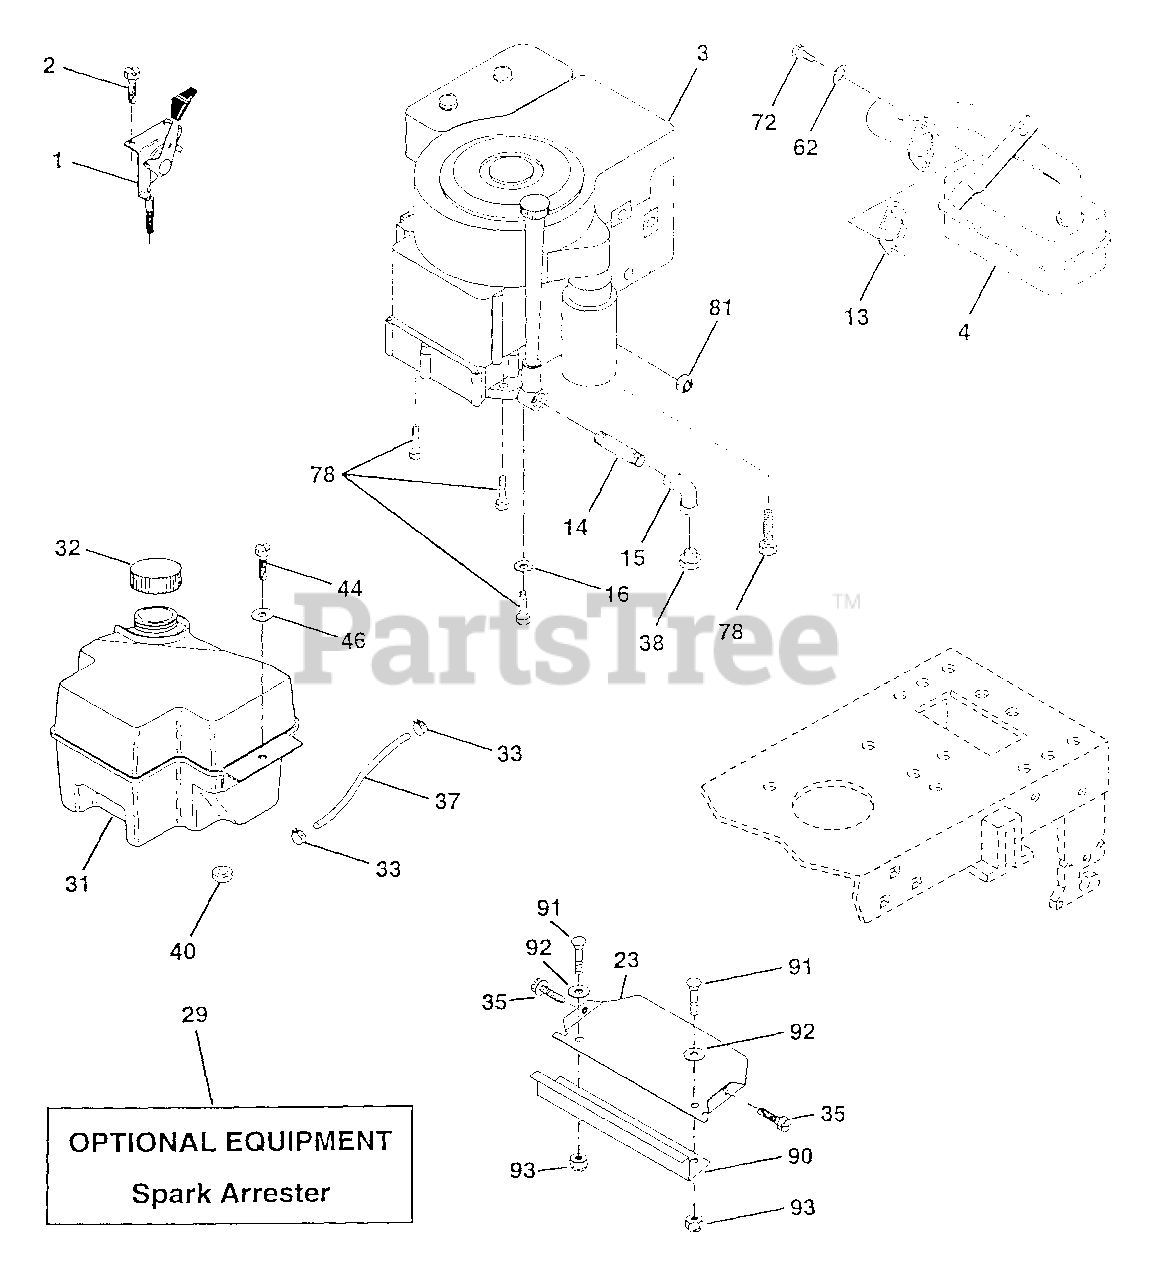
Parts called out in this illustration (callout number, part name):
1	Control Th/ch 23 5 LH Flag (AYP part number)
2	Screw Hex Thd Cut 1/4-20 x 5/8 T
3	Engine B&S
4	Muffler LT B&S 14.5
13	Gasket Eng 1 313 Id Tin Plated
14	Nipple Pipe 3/8 Npt X 3"
15	Elbow Std 90 Degree 3/8-18 Npt
16	Washer Lock Ext Tooth 3/8
23	Shield Heat
29	Kit Spark Arrestor (Flat Scrn)
31	Tank Fuel Front 2 00
32	Cap Asm Fuel W/sym Vented
33	Clamp Hose Black
35	Screw
37	Line Fuel 20"
38	Plug Oil Drain
40	Bushing Snap Nyl Blk Fuel Line (AYP part number)
44	Screw Hexwsh Thdrol 1/4-20 x 3/4
46	Washer 9/32 X 7/8 X 16 Ga
49	Screw Thdrol 3/8-16 x 1
62	Washer Lock Hvy Hlcl Spr 5/16
72	Screw Hexhd Cap 5/16-18 x 3/4
78	Screw Thdrol 3/8-16 x 1-1/4 TYTT
81	Nut Flange 1/4-20 Starter Nut
90	Guard Debris 97
91	Bolt Blk Fin Hex 1/4-20 Unc x 1/2
92	Washer 9/32 x 5/8 x 16 Ga.
93	Nut Lock 1/4 Lge Flg Fr. 5 Zinc (AYP part number)
